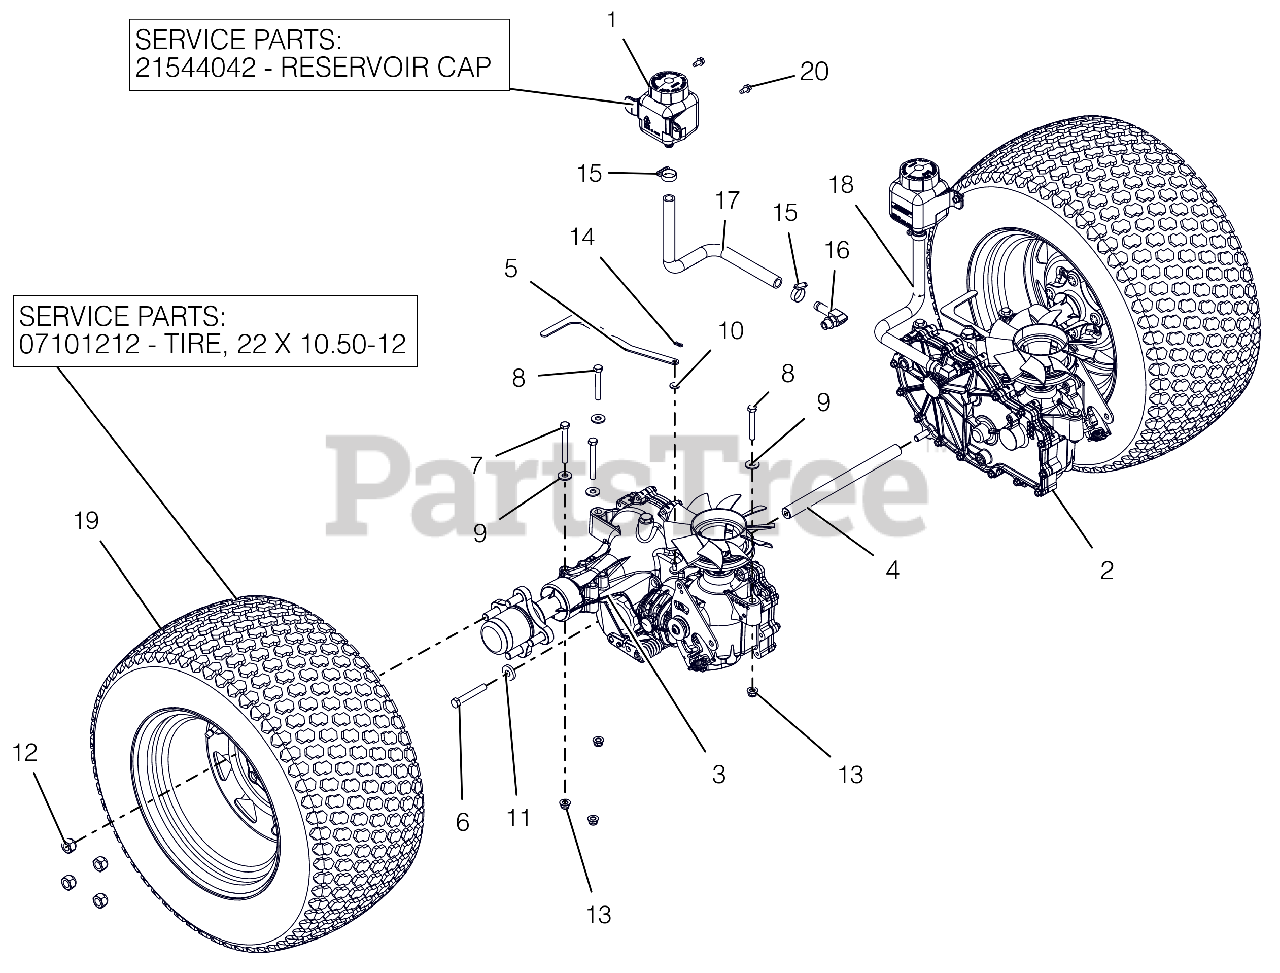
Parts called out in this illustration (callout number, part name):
1	TANK, EXPANSION
1	CAP, HYDRO RESERVOIR REPLAC.
2	TRANSAXLE, ZT3100 LH
3	TRANSAXLE, ZT3100 RH
4	SHAFT, TRANSAXLE SUPPORT
5	BRKT, VALVE DUMP
6	@BLT-HEX .38-16X2.50 GR5 YWZC
7	@BLT-HEX .31-18X2.75 GR5 YWZC
8	@BLT-HEX .31-18X2.25 GR5 YWZC
9	@WSHR-FL-STL.38X.875X.083 YWZC
10	@WSHR-FL-STL.281X.62X.065 YWZC
11	WSHR-FL-STL .406X1.00X.188 YWZ
12	WHEEL NUT .500-20 YZ
13	@NUT-LK-NYL-FLG .31-18 YWZC
14	PIN-HAIR, ENDRIES #25 YWZC
15	CLAMP,.88 DIA. HOSE
16	FITTING, HYD (90 DEG)
17	HOSE, FORMED EXPANSION -HD RH
18	HOSE, FORMED EXPANSION -HD LH
19	ASM, WHL/TIRE 22X10.50-12 K500
19	TIRE, 22X10.50-12
20	SCR-TAP .25-20X.50 HWH TR YWZ
